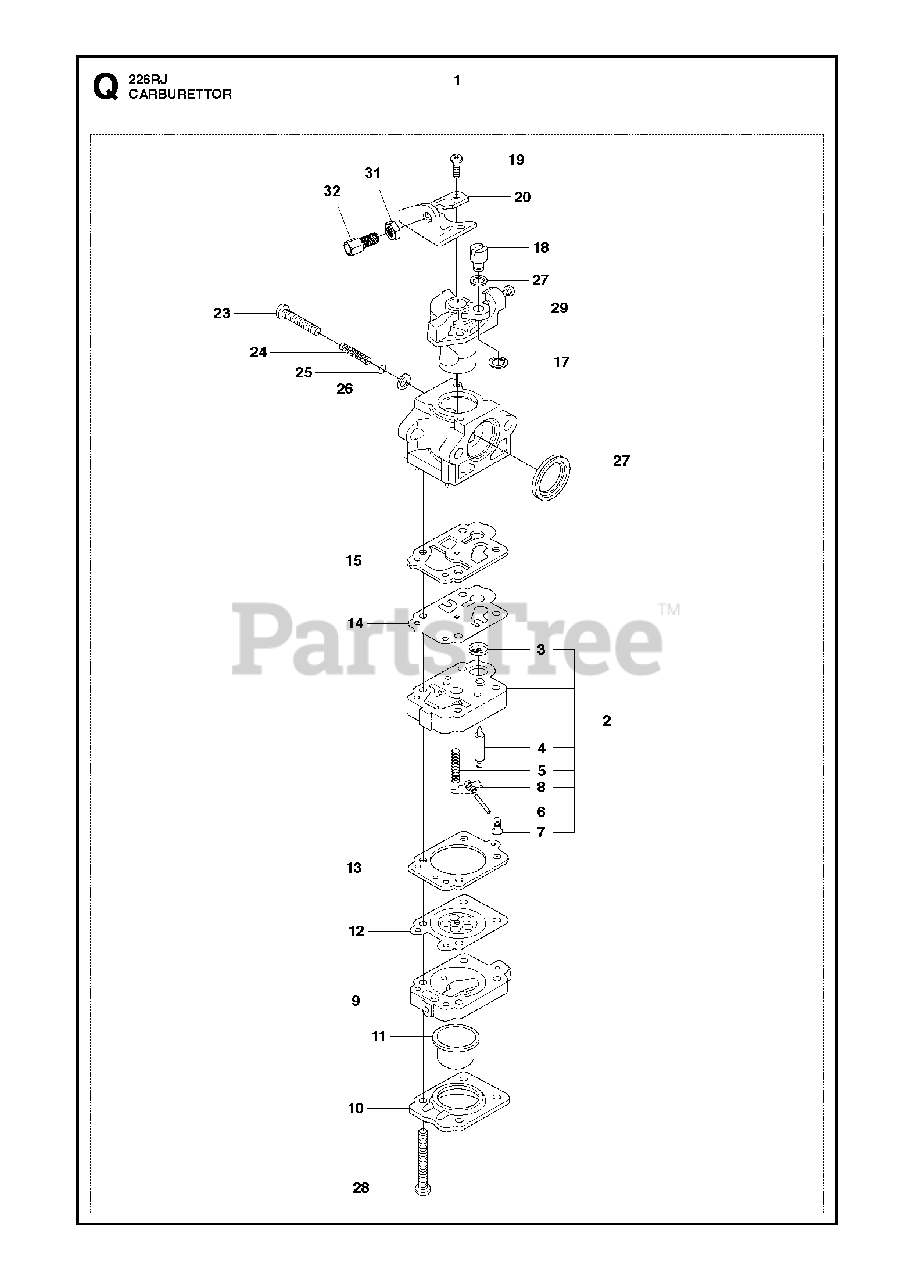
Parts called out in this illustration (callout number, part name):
1	Carburetor
3	SCREEN
4	VALVE INLET
5	Spring
6	PIN
7	Screw
8	LEVER
24	SPRING
27	RING PACKING
31	NUT
32	ADJUSTER
